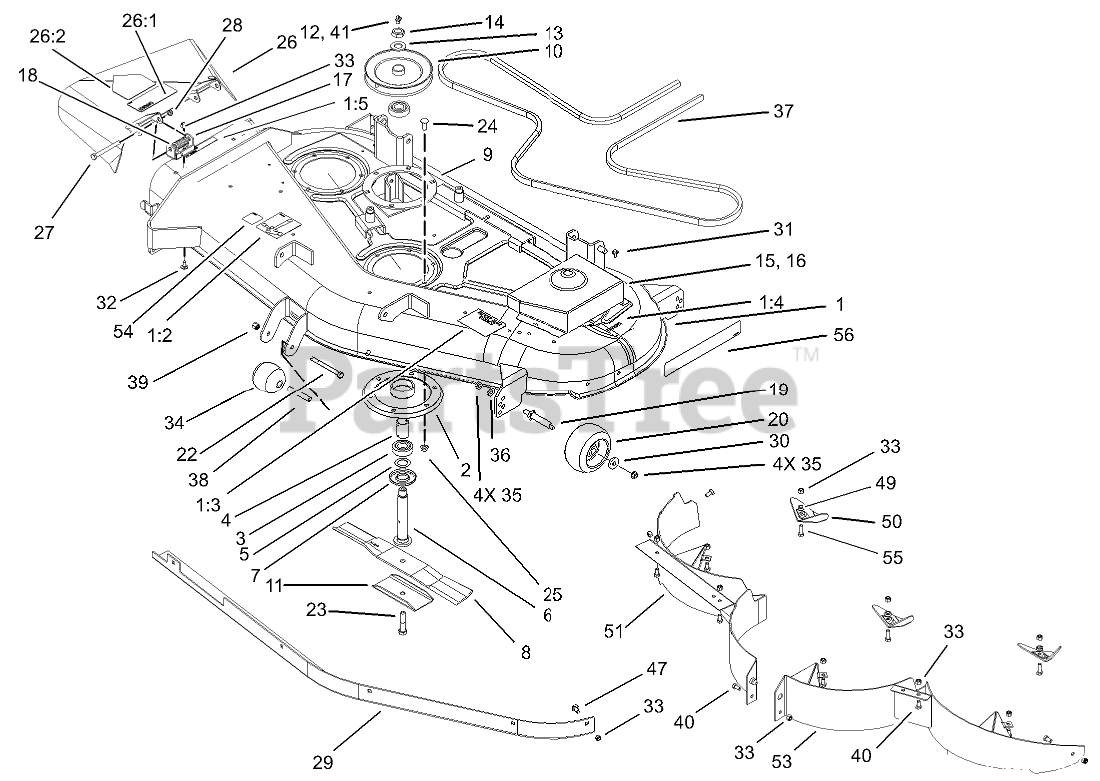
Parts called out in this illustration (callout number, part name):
1	Deck ASM
1:2	DECAL-ROUTING, BELT
1:3	DECAL-ANTI SCALP
1:4	DECAL-DANGER
1:5	DECAL-DANGER
2	HOUSING-SPINDLE
3	BEARING-BALL
4	SPACER-BEARING
5	WASHER-WHEEL
6	SHAFT-SPINDLE
7	SHIELD-BEARING
9	RING-DECK SUPPORT
10	PULLEY/HUB ASM
11	STIFFENER-BLADE
12	FITTING-GREASE
13	WASHER-FLAT
14	NUT-JAM
15	COVER-BELT, LH
16	COVER-BELT, RH
17	BRACKET-PIVOT
18	SPRING
19	SPACER
20	WHEEL-GAGE
22	SCREW-HH
23	SCREW-BLADE
24	SCREW-CARR
25	NUT-HF
26	DEFLECTOR ASM
26:1	DECAL-DANGER
26:2	DECAL-DANGER
27	SCREW-HH
28	NUT-HEX
29	BAFFLE
30	WASHER
31	SCREW-HHFTF
32	SCREW-CARR
33	NUT-LOCK, NI
34	ROLLER
35	NUT-HHF, WHIZ
36	WASHER-BELLEVILLE
37	BELT-DECK (52)
38	TUBE-SPACER, WHEEL
39	NUT-LOCK, NI
40	SCREW-HH
41	FITTING-GREASE
47	SCREW-CARR
49	SPACER
50	PLATE-KICKER
51	RIGHT BAFFLE ASM
52	SCREW-HH
53	LEFT BAFFLE ASM
55	SCREW-HH
56	Decal-Deck
